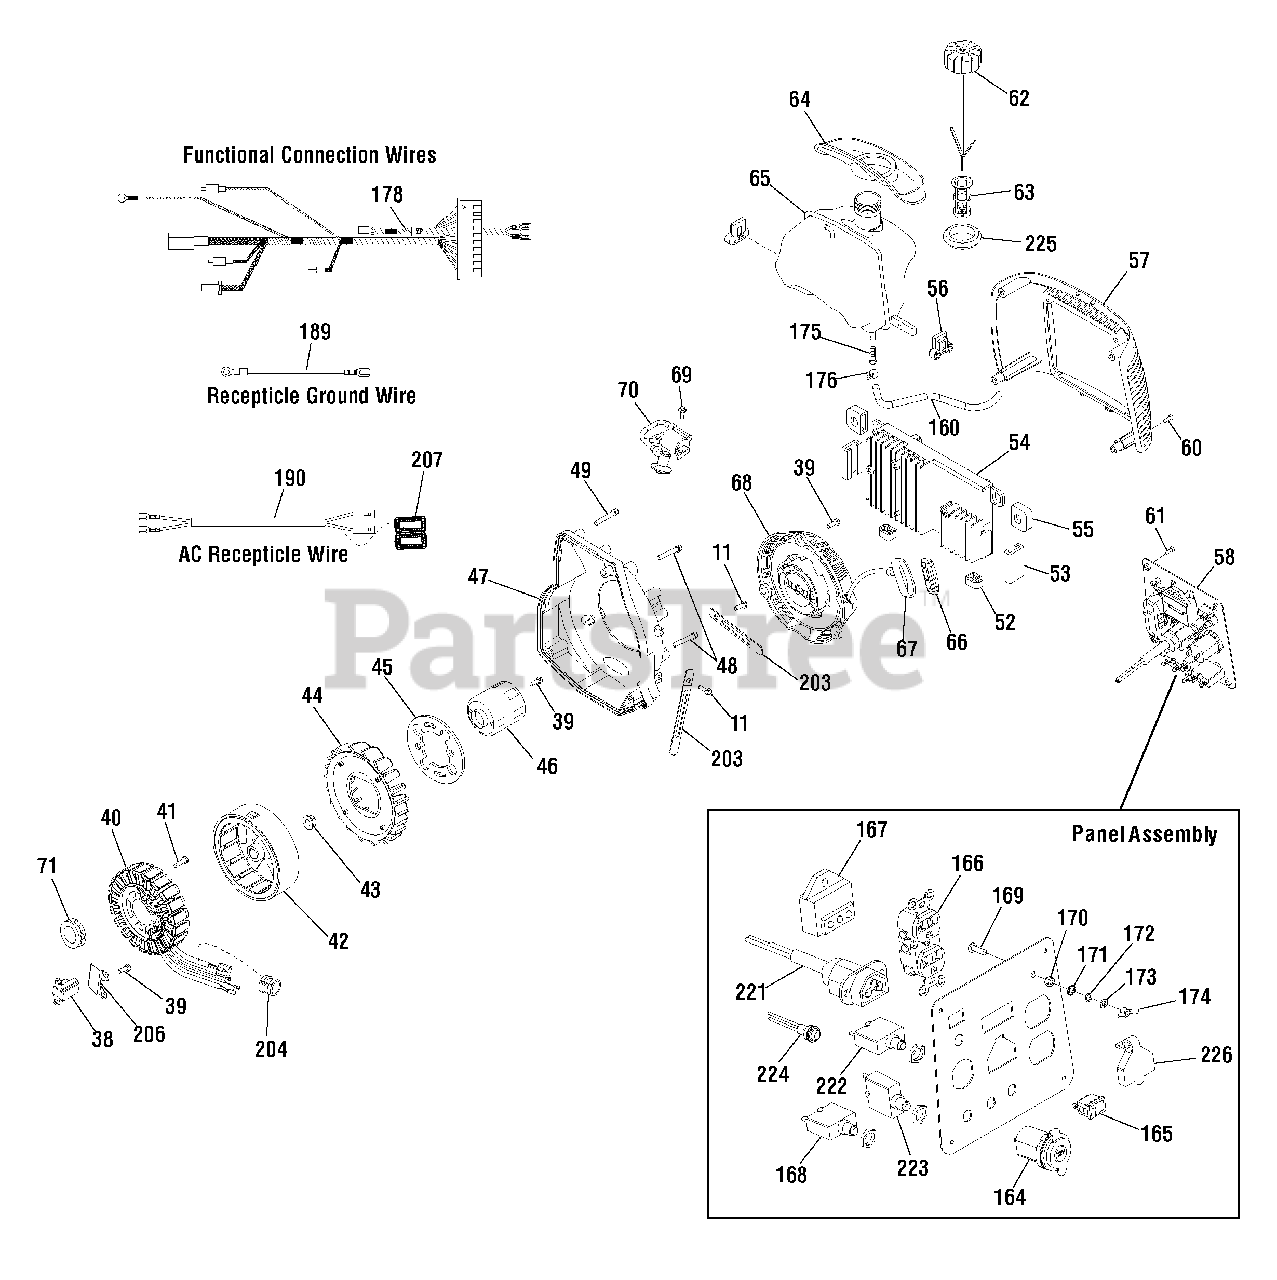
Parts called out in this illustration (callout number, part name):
11	BOLT
38	TRIGGER-IGNITION
45	TERMINAL
47	COVER-FAN
48	BOLT
49	BOLT
52	MOUNT-VIBRATION
53	MOUNT-VIBRATION
55	MOUNT-VIBRATION
56	MOUNT-VIBRATION
58	PANEL-CONTROL
60	SCREW
61	SCREW
63	FILTER-FILLER NECK
64	PAD-FUEL TANK
67	GRIP
68	STARTER-REWIND
69	SCREW
71	SEAL-OIL
167	LIGHT-INDICATOR
168	CIRCUIT BREAKER
175	FILTER-FUEL TANK
176	CLAMP
203	BRACKET
204	COVER-RUBBER
206	PROTECTOR BOARD
222	CIRCUIT BREAKER, 15A
223	CIRCUIT BREAKER, 20A
